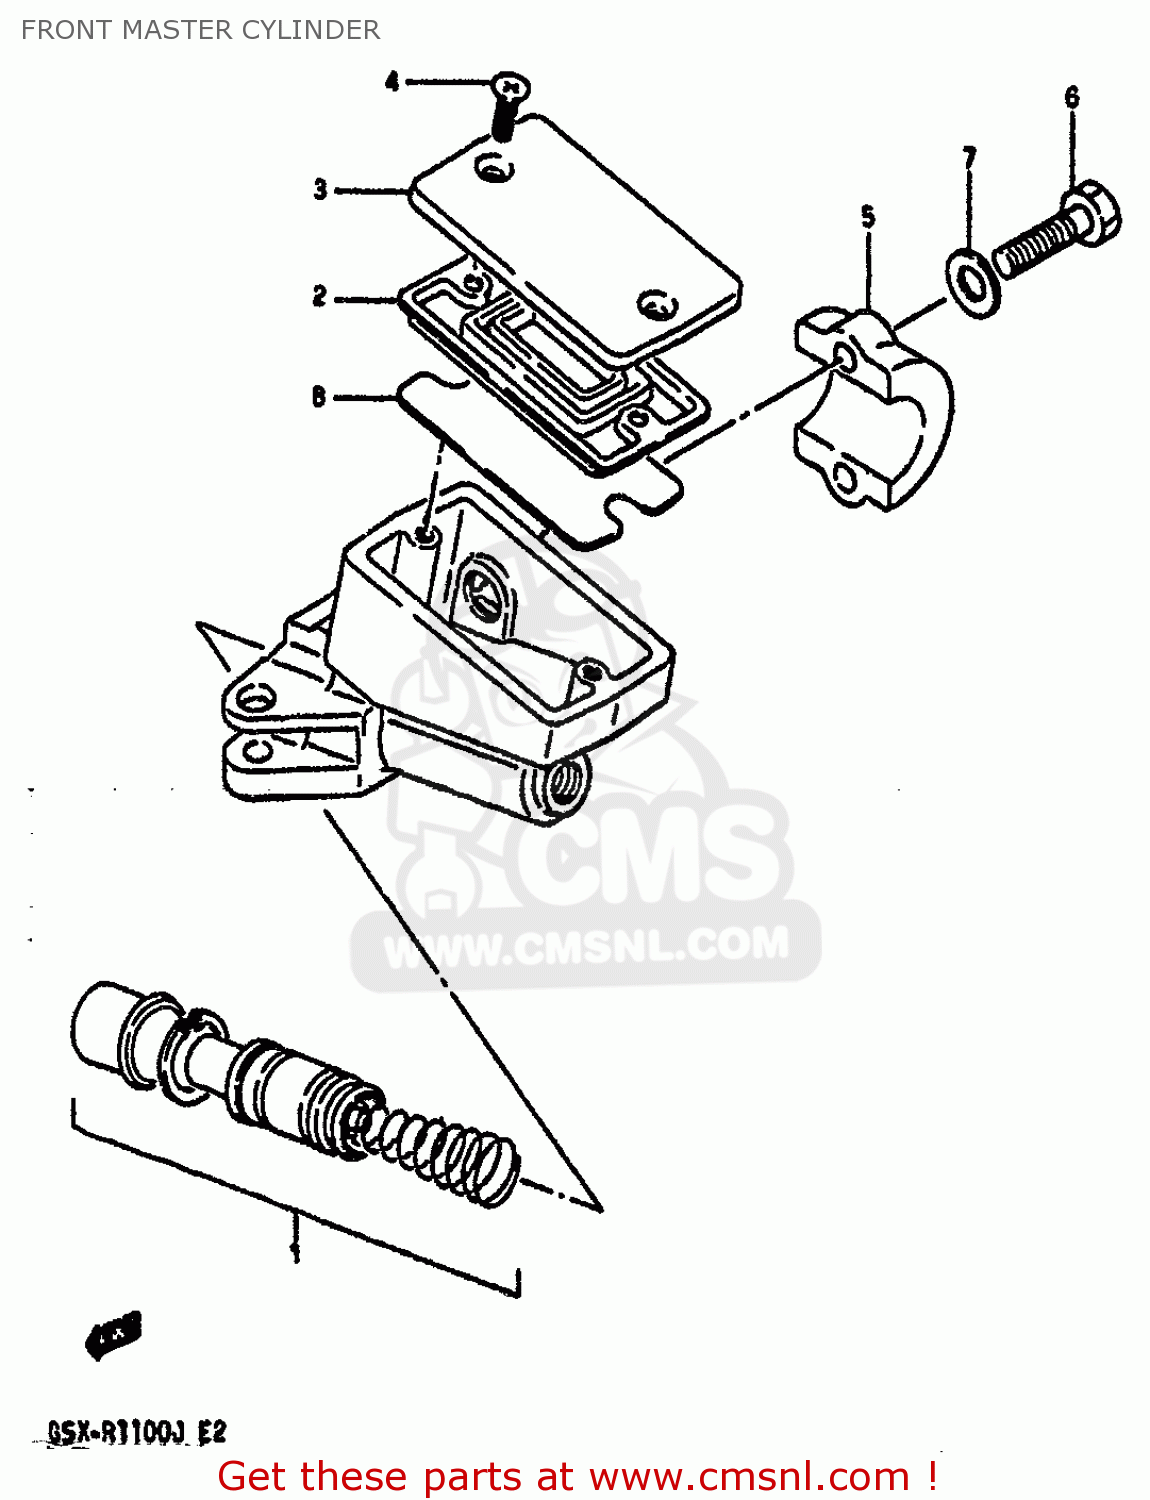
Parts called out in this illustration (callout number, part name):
1	PISTON & CUP SET
2	3
3	CAP
4	SCREW
5	HOLDER,MASTER CYLINDER
6	BOLT
7	WASHER
8	FLOAT
